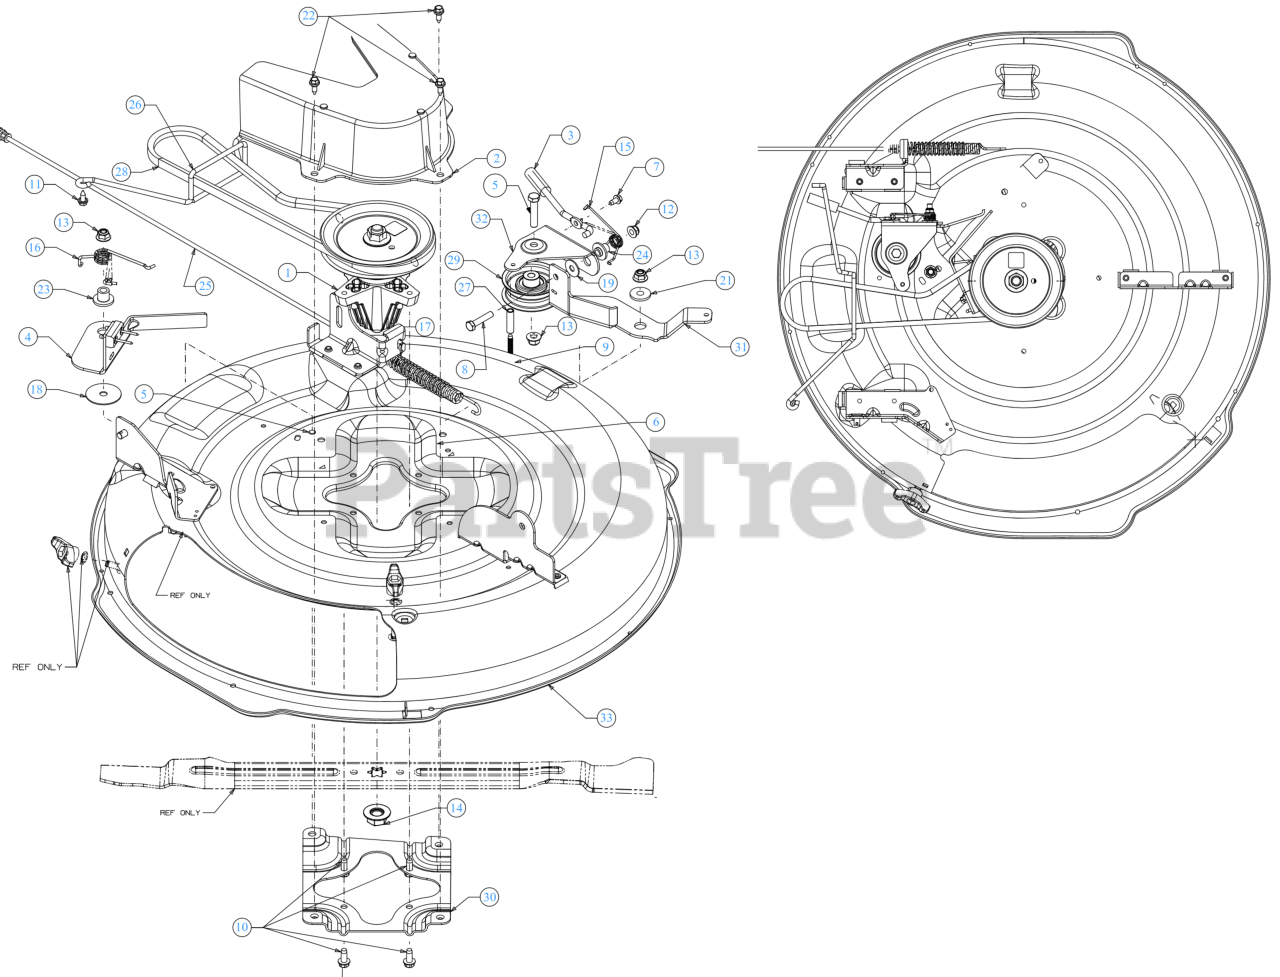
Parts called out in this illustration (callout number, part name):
1	SPINDLE ASSEMBLY
1	Cub Cadet SPINDLE ASSEMBLY
2	DECK BELT COVER ASSEMBLY
3	IDLER GUIDE ROD ASSEMBLY
4	BRAKE PTO BRACKET ASSEMBLY
5	HEX SCREW 3/8-16 x 1.75 GR5
6	SCREW 3/8-16 x 1 GR5
7	SCREW 1/4-20 X.500
8	SCREW 5/16-18 x 1.5 LG
9	SCREW 1/4-20 x 1.750
10	SCREW 5/16-18 x .875
11	SCREW 1/4-20X.625
12	FLANGE LOCK NUT 5/16-18
15	TORSION SPRING PTO
16	TORSION SPRING BRAKE
18	HUB CAP WASHER .406 x 1.92 x .060
19	FLAT WASHER 344X1.00
21	SHOULDER SPACER
22	SHOULDER SCREW
23	DOUBLE SHOULDER SPACER
24	DOUBLE SHOULDER SPACER
26	DECK BELT KEEPER
27	SPACER:.260 x .372 x 1.420
28	V-BELT A SEC 43.5
28	Cub Cadet DECK BELT
28	Genuine Factory Parts DECK BELT
29	FLAT IDLER PULLEY 2.75 OD
31	IDLER BRACKET FLOATING LOWER
